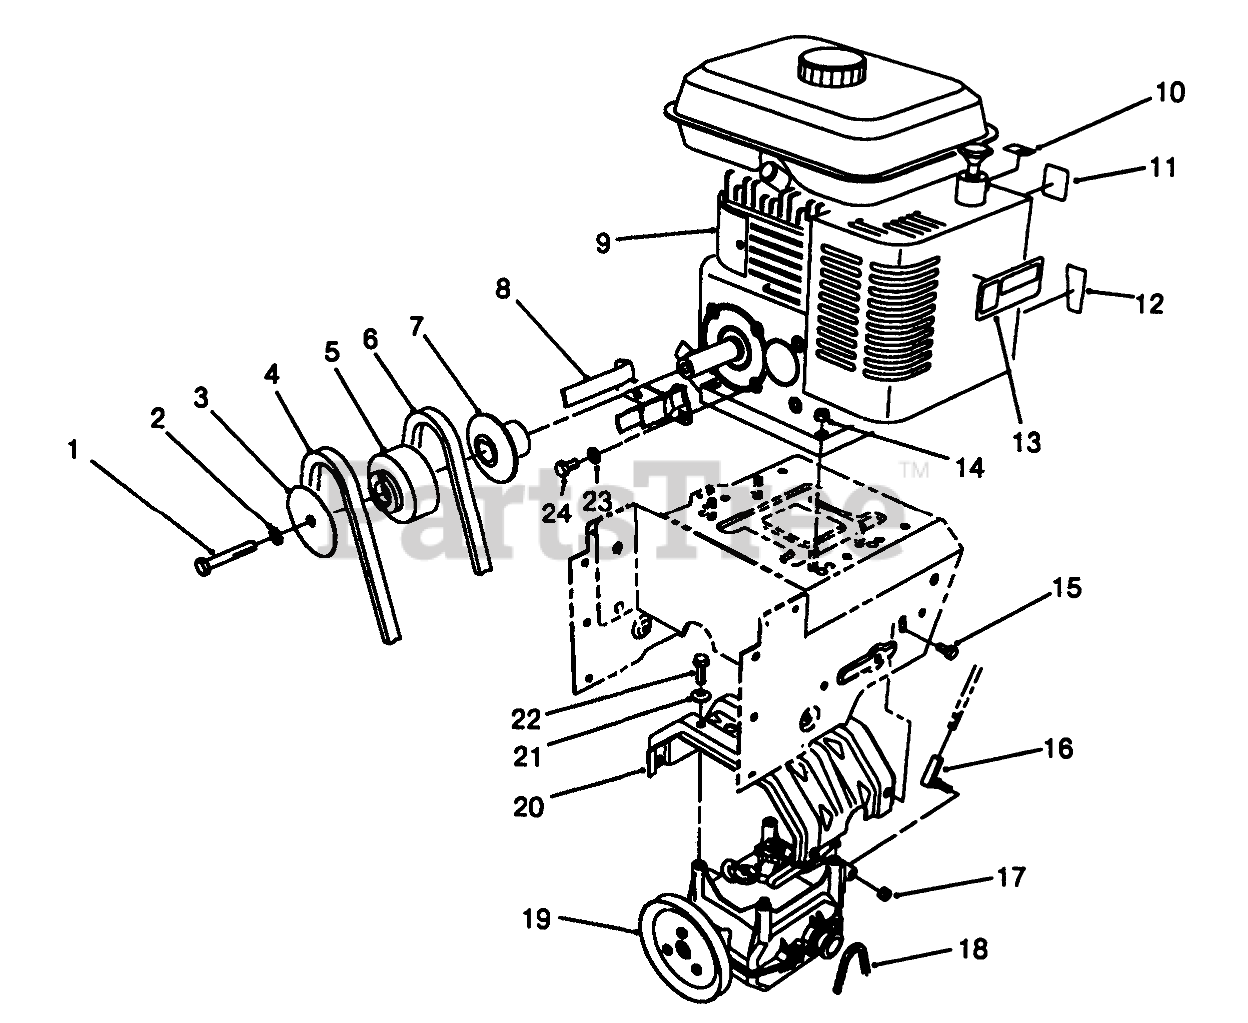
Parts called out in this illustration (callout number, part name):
1	SCREW-HH
2	WASHER-LOCK
3	SHEAVE-HALF,IMPELLER
4	V-BELT, IMPELLER
5	ENGINE PULLEY,CENTER
6	TRACTION BELT
7	SHEAVE-HALF,TRACTION
8	Guide-Belt
9	Engine-6 hp.
10	DECAL-CHOKE
11	DECAL-PRIMER/CHOKE
12	DECAL-THROTTLE
13	Decal-Hot
14	NUT-HF
15	SCREW-HHF
16	JOINT-BALL
17	NUT-LOCK
18	CHAIN
19	Transmission Assembly
20	Frame-Transmission
21	WASHER-SPRING
22	SCREW-HWHTF
23	WASHER-LOCK
24	SCREW-HH
